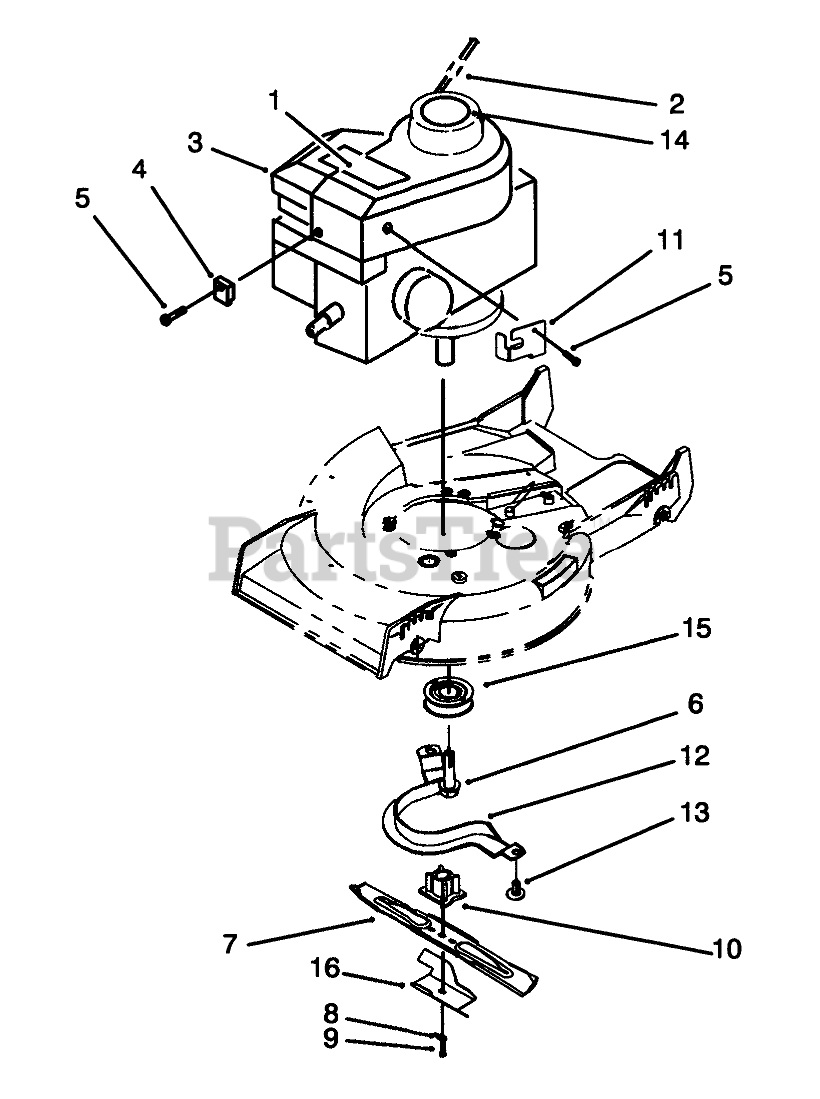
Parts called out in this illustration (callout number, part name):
1	DECAL - ENGINE
2	STOP-ROPE
4	CASING CLAMP F/W ENGINE
5	CLAMP SCREW F/W ENGINE
6	SCREW-HWH
7	Blade
8	WASHER-LOCK
9	SCREW-BLADE
10	BLADE RETAINER
11	BRACKET - CABLE
12	Guide-Belt
13	SCREW-HWHTF
14	Decal-Toro
15	Pulley-Drive
16	Accelerator
